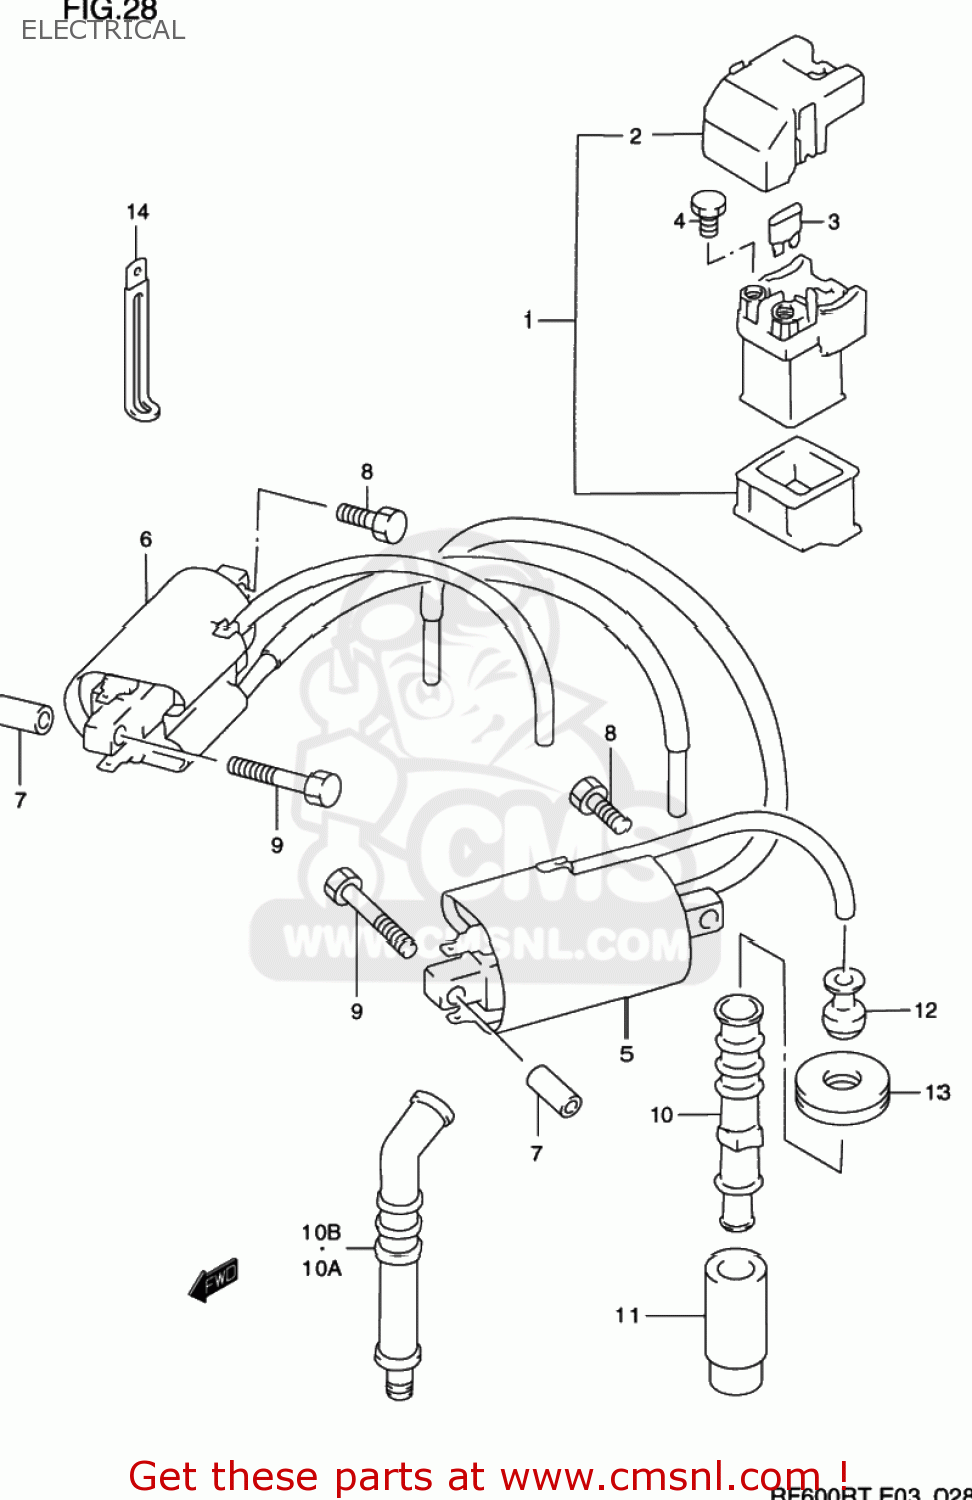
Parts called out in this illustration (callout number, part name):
1	RELAY ASSY,STARTING MOTOR
2	COVER,RELAY ASSEMBLY
3	FUSE(30A)
4	SCREW(6X8)
5	COIL ASSEMBLY,IGNITION NO
6	COIL ASSEMBLY,IGNITION NO
7	SPACER(6.2X15.5X16.5)
8	BOLT
9	BOLT
10	CAP,SPARK PLUG
10A	CAP,SPARK PLUG
10B	CAP ASSY,SPARK PLUG
11	SEAL,SPARK PLUG
12	SEAL,HIGH TENSION CORD
13	COVER,SPARK PLUG CAP
14	CLAMP
